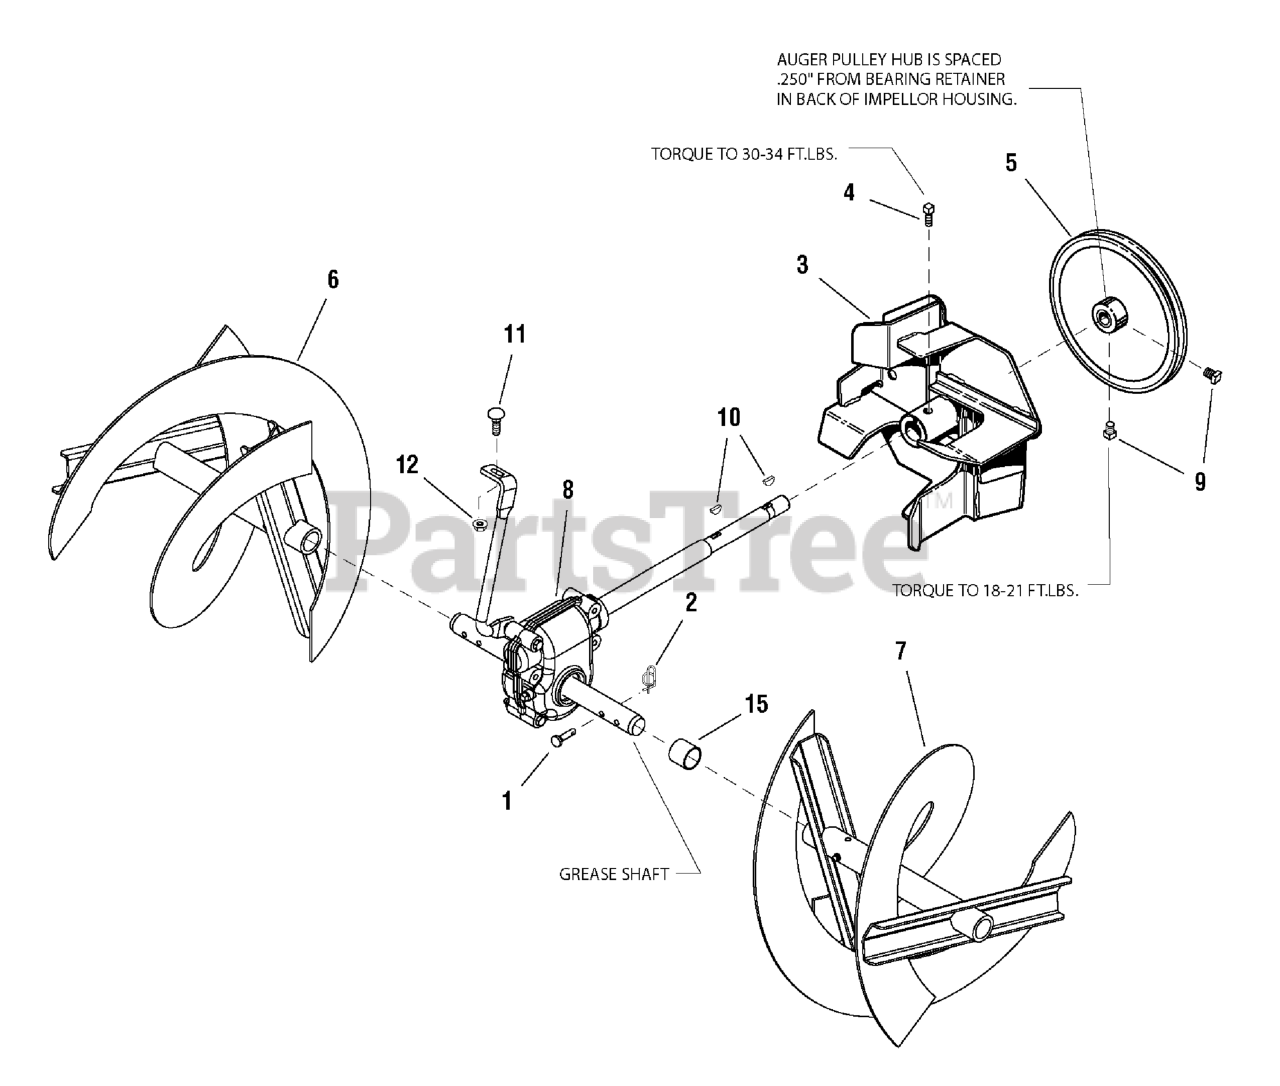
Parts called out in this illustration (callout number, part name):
1	PIN, Shear
2	COTTER PIN, 1/4" Self Locking
3	IMPELLER ASSEMBLY
4	SCREW, Set Square Head Cup Point, 3/8-16 x 1/2, G8
6	AUGER ASSEMBLY, 24" & 26" R.H.
6	AUGER ASSEMBLY, 28" & 30" R.H.
7	AUGER ASSEMBLY, 24" & 26" L.H.
7	AUGER ASSEMBLY, 28" & 30" L.H.
8	GEAR BOX ASSEMBLY
9	SCREW, Set Square Head Cup Point, 5/16-18 x 1/2, G8
10	KEY, Woodruff
11	CARRIAGE BOLT, 5/16-18 x 3/4, G5
12	NUT, Hex Flange Whiz Lock, 5/16-18
15	TUBE
